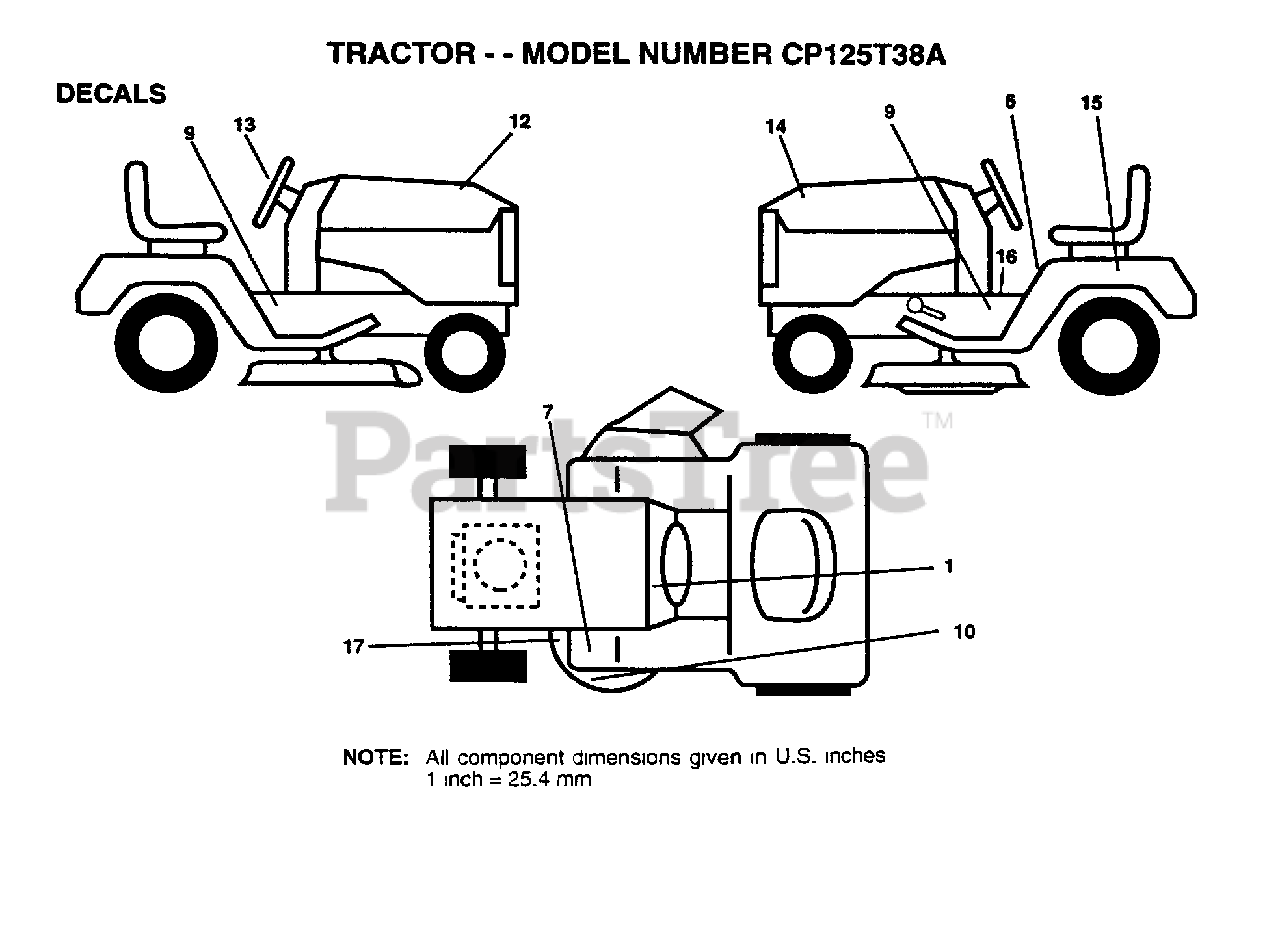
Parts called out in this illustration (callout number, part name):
1	DECAL.DASH.INST.
6	DECAL
9	"DECAL.CHASSIS.38"""
12	DECAL.HD.RH.CPARK
14	DECAL.HD.LH.CPARK
15	DECAL
16	DECAL BRAK PARK
17	DECAL
